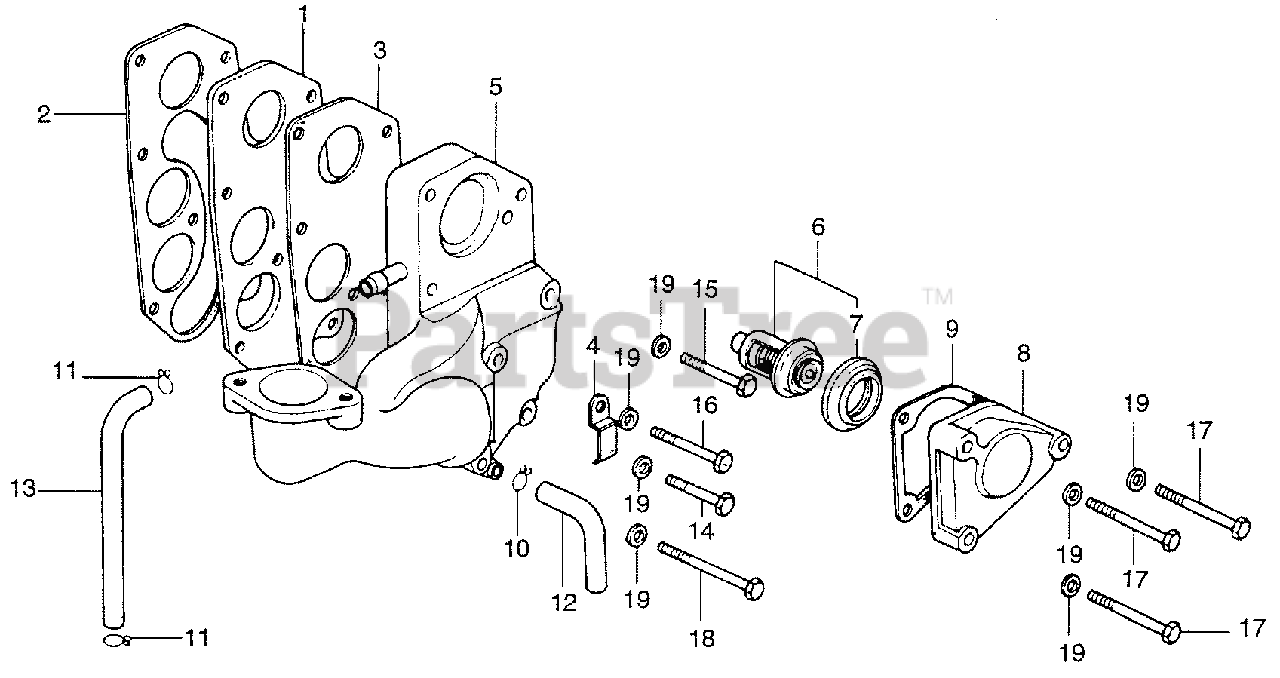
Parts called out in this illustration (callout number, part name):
1	PLATE, EX. CHAMBER
2	GASKET, EX. CHAMBER
3	GASKET, EX. CHAMBER
4	CLAMP, FUEL TUBE (NOT AVAILABLE)
5	MANIFOLD, IN. (NOT AVAILABLE)
6	THERMOSTAT ASSY.
7	RUBBER, THERMOSTAT
8	COVER, THERMOSTAT *NH8* (DARK GRAY) (NOT AVAILABLE)
9	GASKET, THERMOSTAT
10	CLIP, TUBE (B8)
11	CLIP, TUBE (C11) (NOT AVAILABLE)
12	TUBE, WATER CHECK (NOT AVAILABLE)
13	TUBE, BYPASS (NOT AVAILABLE)
14	BOLT, HEX. (6X28)
15	BOLT, HEX. (6X32)
16	BOLT, HEX. (6X35) (NOT AVAILABLE)
17	BOLT, HEX. (6X45)
18	BOLT, HEX. (6X50)
19	WASHER, PLAIN (6MM)
